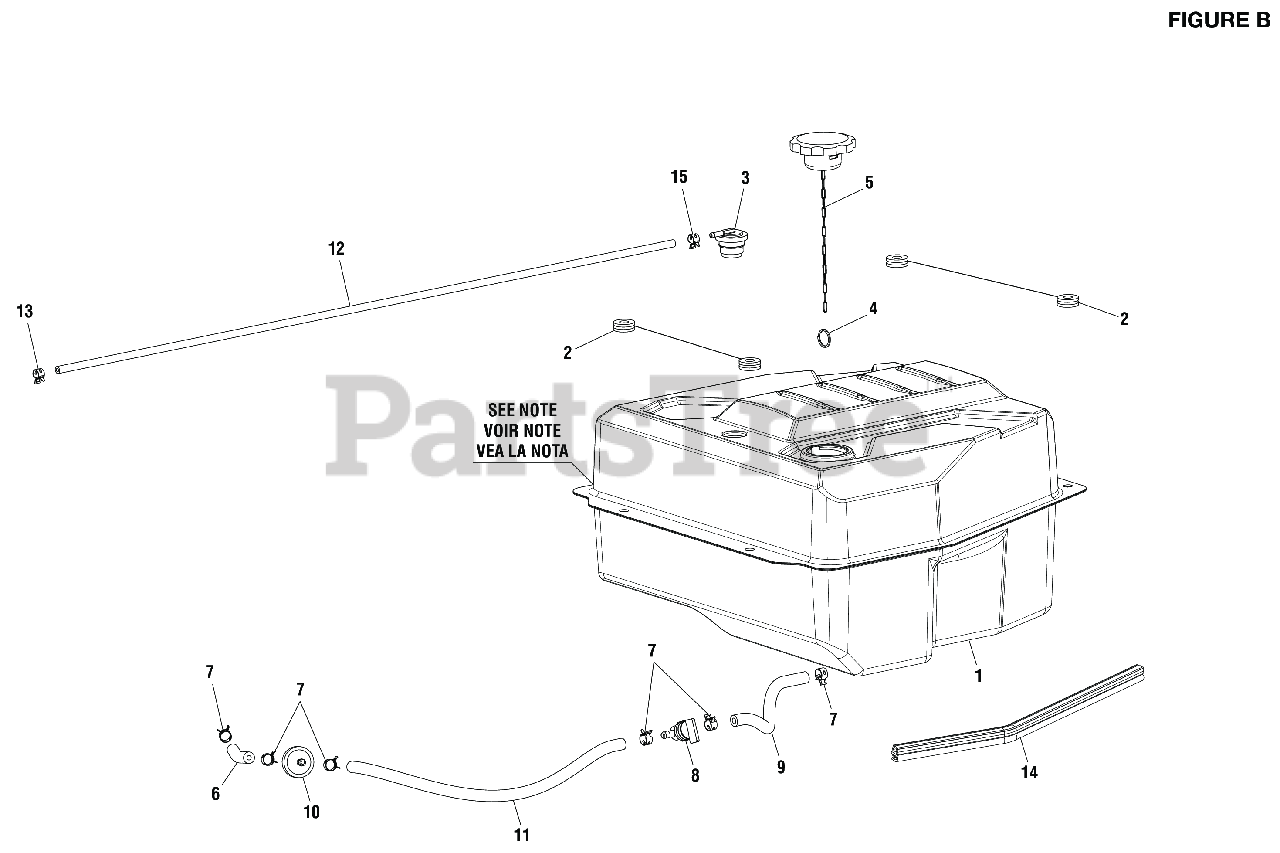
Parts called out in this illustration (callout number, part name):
1	FUEL TANK 8 GALLON W/ BUSHINGS/SPACERS
2	Bushing w/Insert
3	Fuel Tank Vent Valve (PS905055SA)
4	Ring Clip
5	Fuel Cap Assembly
6	FUEL HOSE, 1/4 X 60MM
7	Fuel Line Clamp (1/2 in.).
8	FUEL SHUT OFF VALVE 180 DEGREE
9	FUEL HOSE, 220MM X 1/4IN
10	Fuel Filter Inline (1/4 in.)
11	FUEL HOSE, 5MM X 430MM
12	VAPOR HOSE TAPERED 825MM
13	Fuel Line Clamp (3/8 in.).
14	BONDED RUBBER, WEATHER STRIPPING
15	Fuel Line Clamp (7/16 in., BM903611)
